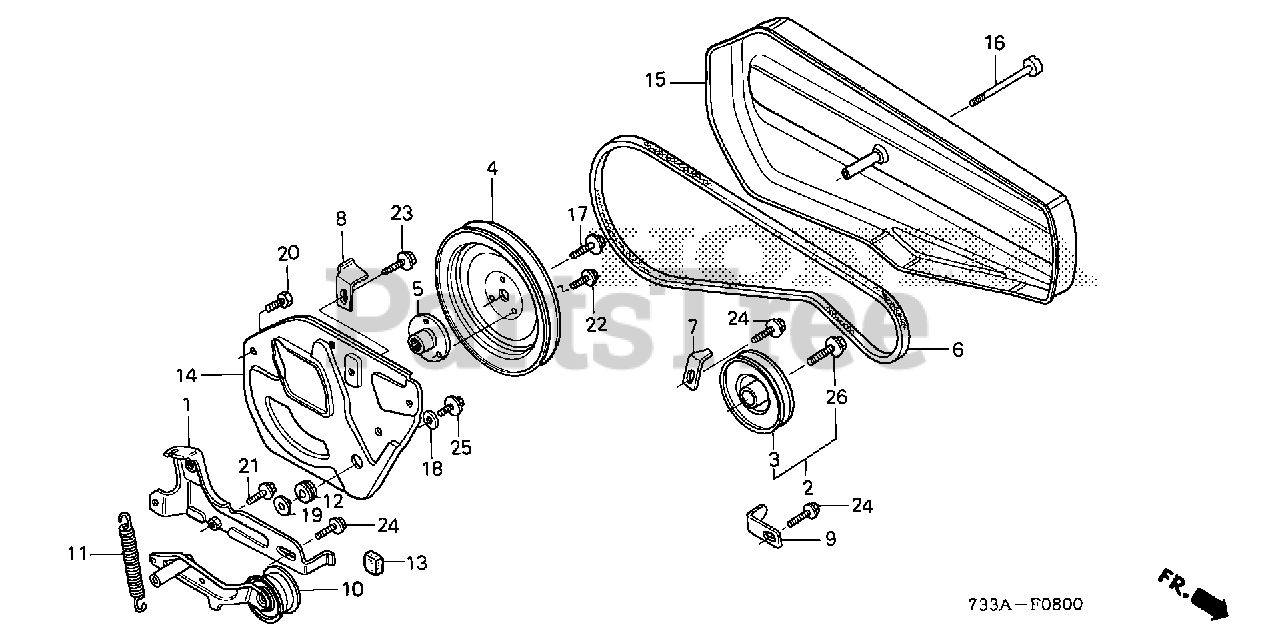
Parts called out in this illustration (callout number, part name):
1	STAY, ENGINE
2	PULLEY SET, DRIVE (NOT AVAILABLE)
3	PULLEY, DRIVE
4	PULLEY, DRIVEN (141MM)
5	BOSS, DRIVEN PULLEY
6	V-BELT (37)
7	STOPPER, BELT (UPPER)
8	STOPPER C, BELT
9	STOPPER, BELT (LOWER)
10	ARM, TENSIONER
11	SPRING, BELT TENSIONER
12	GROMMET, WIRE HARNESS
13	HOLDER, FUSE STAY (NOT AVAILABLE)
14	STAY, BELT COVER
15	COVER, BELT *R280* (POWER RED)
16	BOLT, BELT COVER (NOT AVAILABLE)
17	BOLT, FLANGE
18	WASHER (8MM)
19	WASHER, NUMBER BRACKET MOUNTING
20	BOLT, HEX. (6X8)
21	BOLT-WASHER (6X16)
22	BOLT, FLANGE (6X10)
23	BOLT, FLANGE (6X12)
24	BOLT, FLANGE (8X16)
25	BOLT, FLANGE (8X20)
26	BOLT, FLANGE (8X22)
